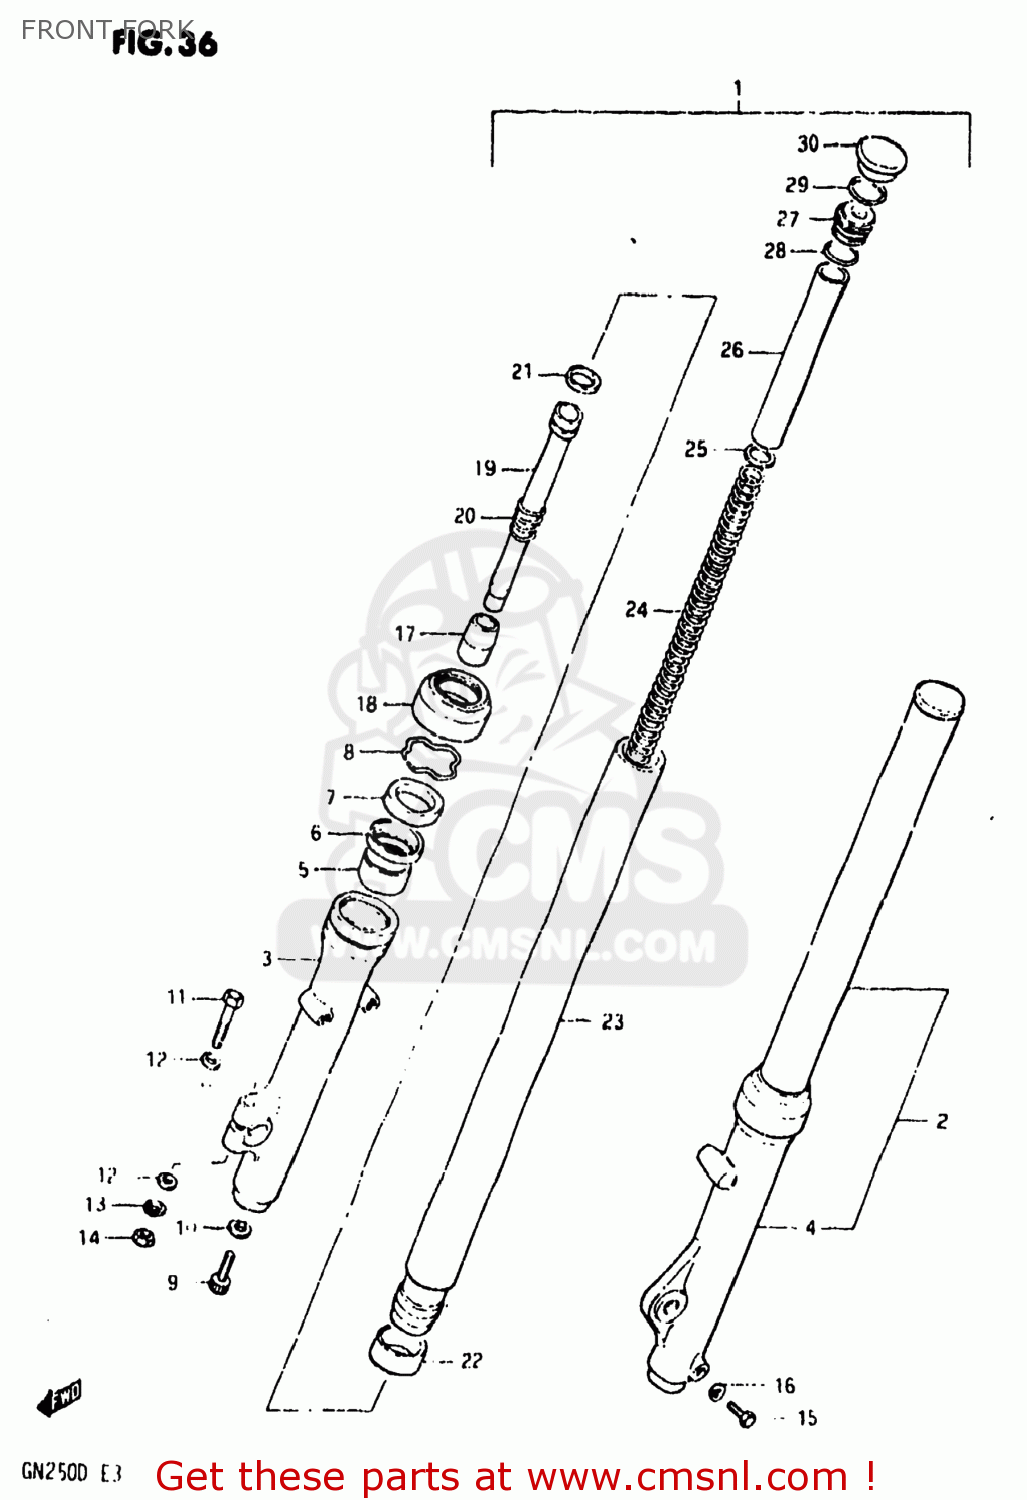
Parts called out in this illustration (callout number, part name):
1	DAMPER ASSEMBLY,RIGHT
2	DAMPER ASSEMBLY,FRONT FORK,LEFT
3	TUBE,FORK,OUTER,RIGHT
4	TUBE,FORK,LEFT,OUTER
5	BUSH,GUIDE
6	SPACER,OIL SEAL
7	OIL SEAL,FRONT FORK
8	CIRCLIP,FORK OIL SEAL
9	BOLT(8X27)
10	GASKET (NAS)
11	BOLT 8X50
12	WASHER
13	LOCK WASHER
14	NUT
15	BOLT
16	GASKET,DRAIN,PLUG (NAS)
17	PIECE,OIL LOCK
18	DUST SEAL
19	CYLINDER
20	SPRING,REBOUND
21	RING,PISTON
22	BUSH
23	TUBE,INNER
24	SPRING
25	SEAT,SPRING
26	SPACER,FRONT FORK SPRING
27	SEAT,SPRING
28	O RING
29	RING,FRONT FORK PISTON
30	CAP
